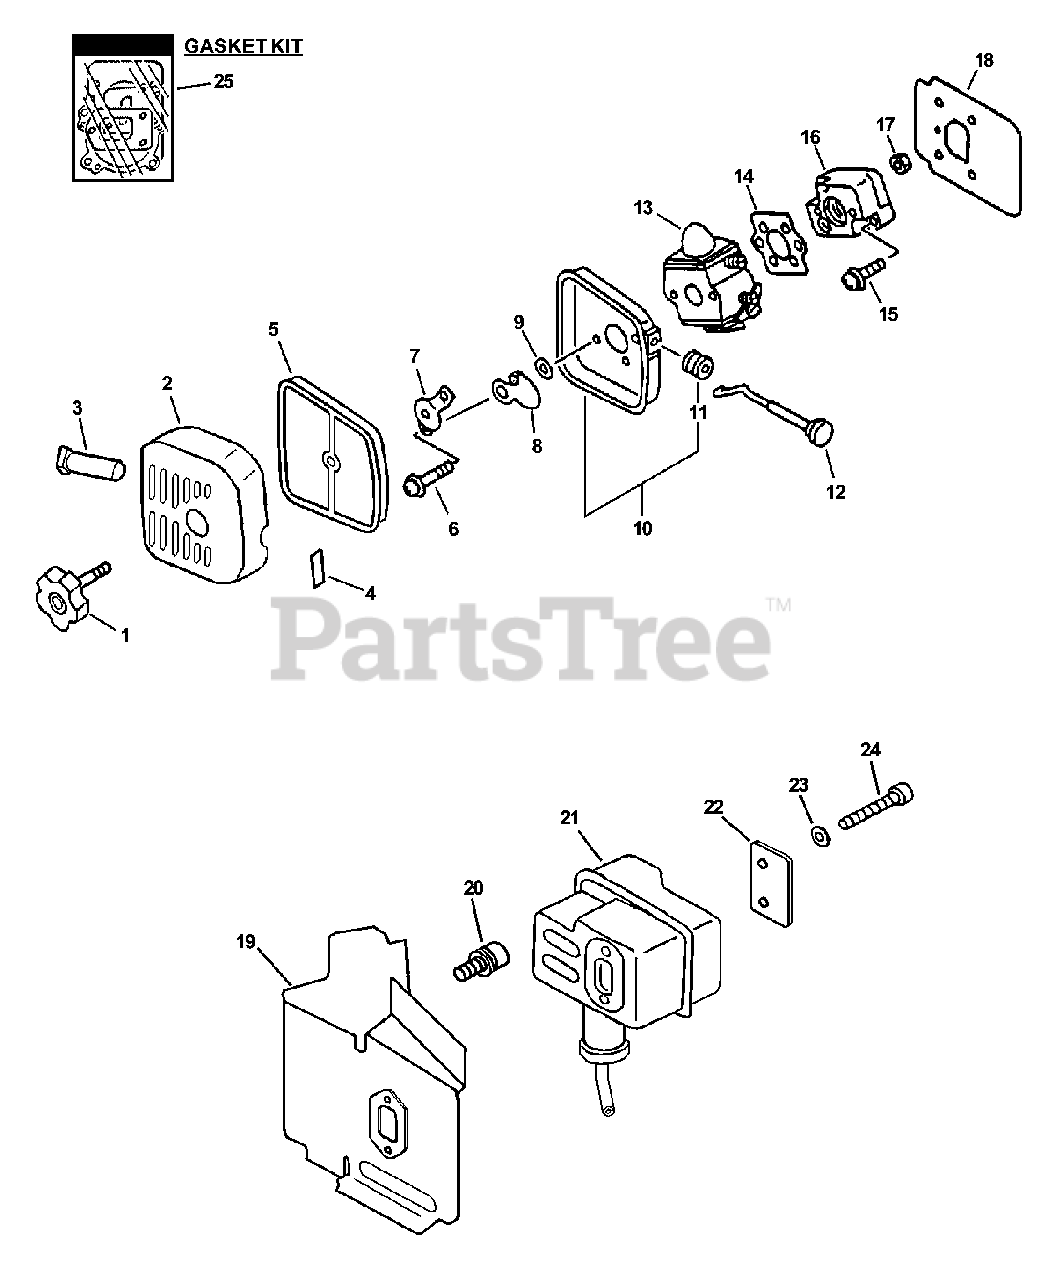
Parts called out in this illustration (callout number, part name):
1	THUMBSCREW
2	COVER, AIR FILTER
4	LABEL - CHOKE
5	FILTER, AIR - HEAVY DUTY
6	SCREW - 5X57
7	PLATE, PREVENT
8	SHUTTER, CHOKE
9	WASHER - 5
10	CASE, AIR FILTER
12	ROD, CHOKE
13	CARBURETOR C1U-K54A
14	GASKET, INTAKE
15	SCREW - 5X20
16	INSULATOR, INTAKE
18	SHIELD, INTAKE
19	SHIELD, EXHAUST
20	SCREW - 4X8
21	MUFFLER
23	WASHER - 5
24	SCREW - 5X70
28	GASKET KIT
